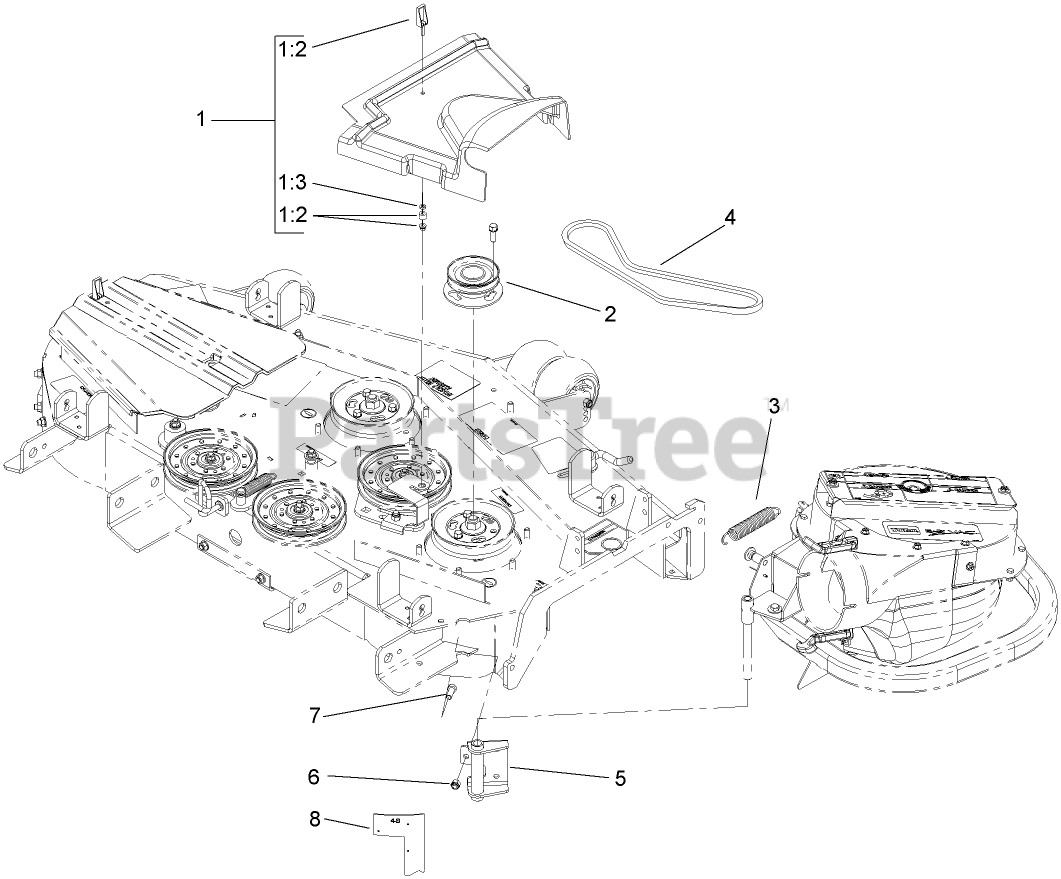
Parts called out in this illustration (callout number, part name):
1	BELT COVER ASM
1:2	LATCH-SWELL
1:3	WASHER
2	PULLEY ASM
3	SPRING-EXTENSION
4	BELT-V
5	BLOWER HINGE ASM
6	NUT-LOCK, NI
7	SCREW-HH
8	TEMPLATE
